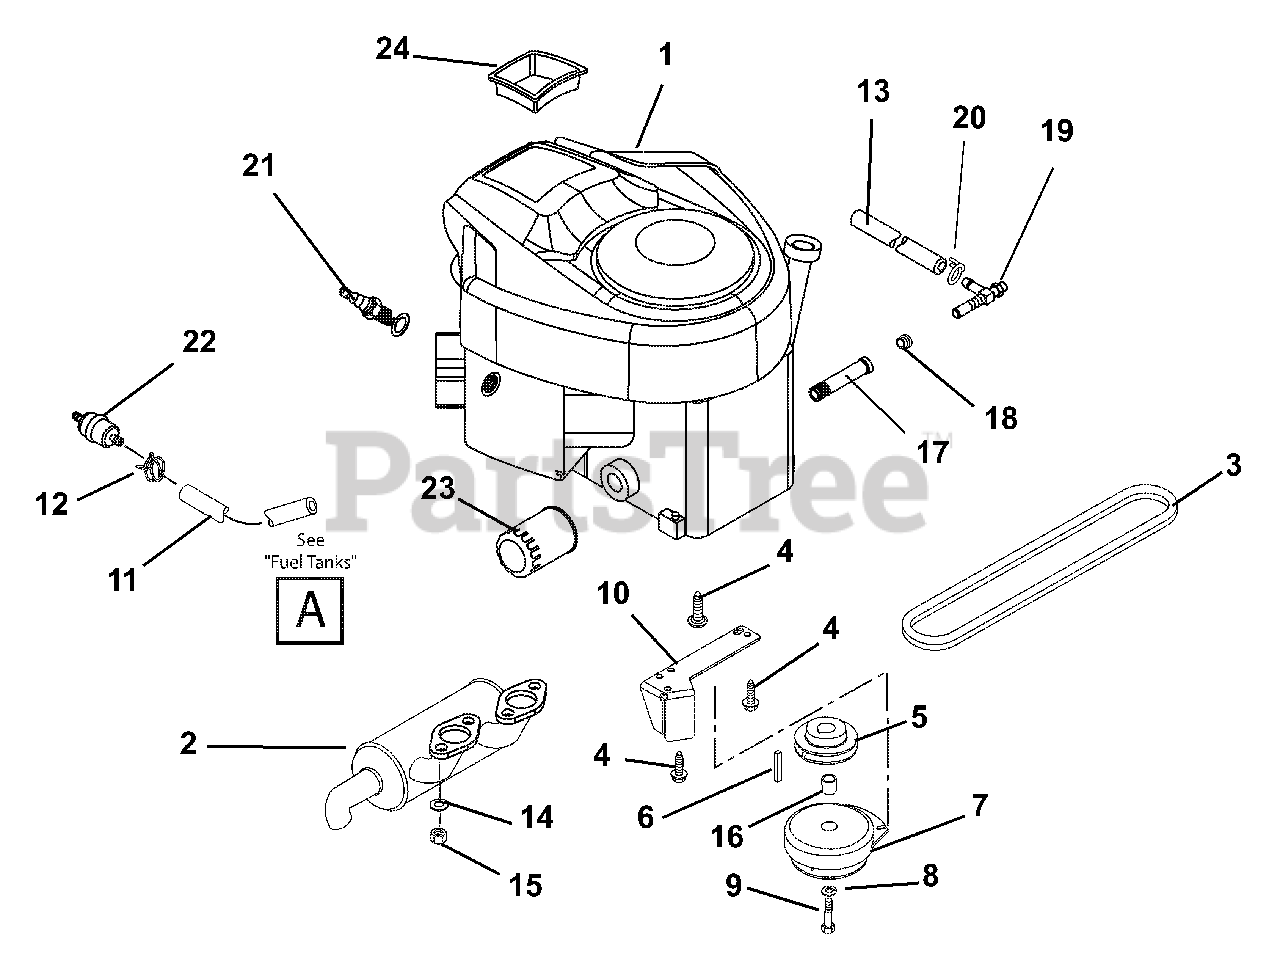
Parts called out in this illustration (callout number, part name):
1	20HP KOHLER COURAGE TWIN
2	MUFFLER, KOHLER TWIN
3	V-BELT, HA-RAW EDGE
4	BLT, 38-16X1 6-LOBE PH TRX YZ
5	PLY-V 4.OO X 1.00
6	KEY-SQ .25X.625X.25 SAE 8630
7	CLUTCH, ELEC 1.000 ID 5219-55
8	@WSHR-LK .44X.109 REG YWZC
9	BLT-HEX .44-20X3.00 GR5 YWZC
10	STOP, CLUTCH
11	GAS LINE-BULK 1/4" I.D.
12	CLAMP-HOSE WIRE .490/.510X.116
13	TUBE, OIL DRAIN 8" CLEAR VINYL
14	@WSHR-LK .31X.078 REG YWZC
15	NUT-HEX M8-1.25 YWZC
16	SPACER 1.005X1.5075X.375
17	NIPPLE, PIPE .375NPT X 4.00
18	ADAPTER, 3/8 NPTF
19	DRAIN, 1/2" OIL
20	CLAMP,.88 DIA. HOSE
21	PLUG, SPARK
22	FILTER, FUEL
23	FILTER, OIL - KOH CV20
24	FILTER, AIR-COURAGE TWIN
